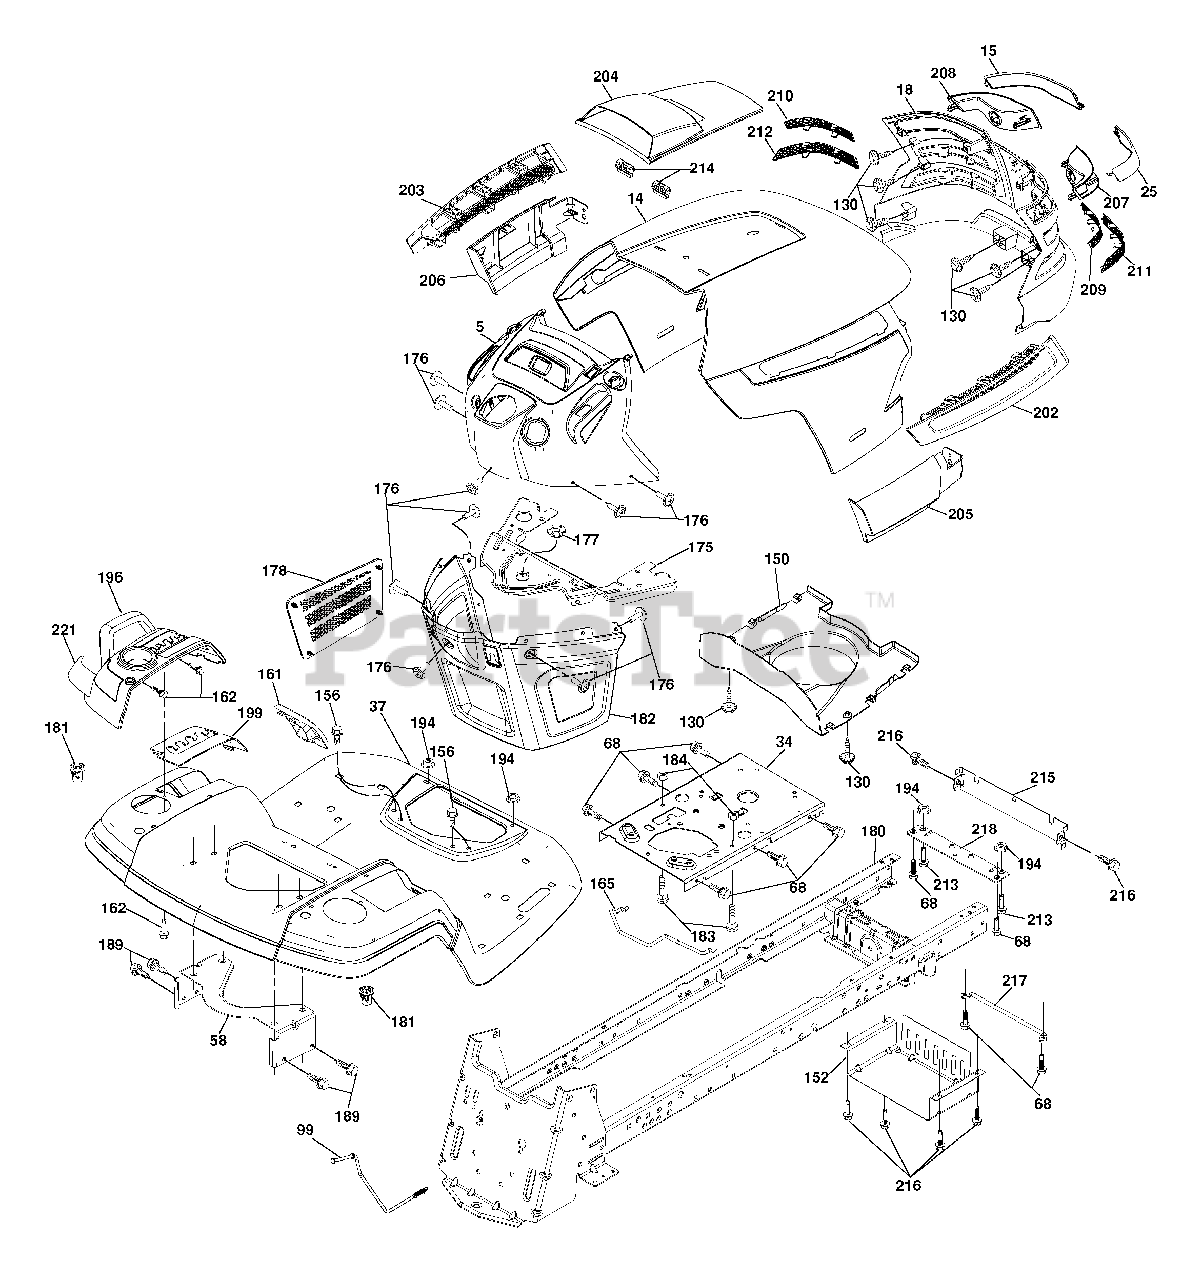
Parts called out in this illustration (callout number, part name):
2	Drawbar
5	Dash
14	Hood
17	Screw 3/8-16 x .75
18	Grille
34	Plate Engine
37	Fender
58	Bracket Fender
99	Rod Bypass Asm.
130	Screw 10 x 3/4 Single Lead-Hex
139	Bolt Shoulder 5/16-18
148	Bumper Extrusion
150	Duct Heat Hood
152	Shield Browning/Debris
161	Console Fuel Window
162	Screw Hex Wsh Hi-Lo 1/4 x 1/2
165	Bracket Support Tank
175	Crossmember
176	Screw 10-24 x 5/8 Wshd Qdrx
177	Bushing Steering
178	Cargo Asm. Net
180	Chassis
181	Bushing Mtg. Fender Crgo.
182	Dash Lower
189	Screw 5/16-18 x 3/4
195	Plug 12V Adapter Caplug
196	Console Asm. Deck Lift
199	Plate Deck Lift
202	Vent Side Hood RH
203	Vent Side Hood LH
204	Vent Asm Hood Top
205	Skirt Hood Side RH
206	Skirt Hood Side LH
209	Insert Hex Top RH
210	Insert Hex Top LH
211	Insert Hex Bottom RH
212	Insert Hex Bottom LH
213	Vent Top Hood
214	Clip Retainer
215	Cover Chassis Front
216	Screw 5/16-18 x 1/2
217	Rod Pivot
219	Stud Fastener
220	Nut Lock
